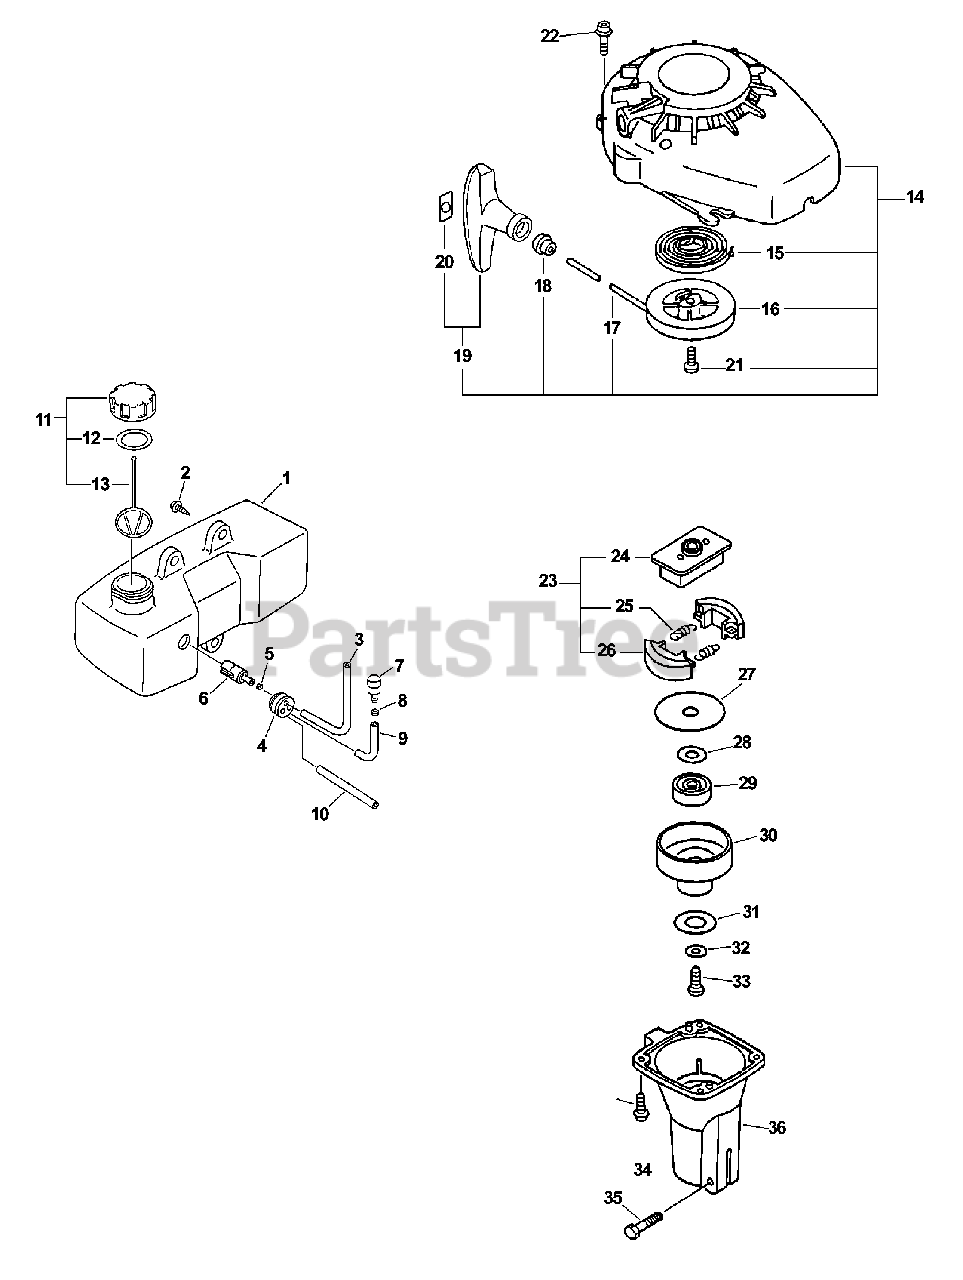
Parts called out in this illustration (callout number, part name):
1	FUEL TANK ASSY
2	SCREW - 5X15
3	PIPE - 3X5X210 -- BLACK
4	GROMMET
5	CLIP - 6
6	FILTER, FUEL
7	VENT, FUEL TANK
8	CLIP - 5.5
9	PIPE - 3X5X70 -- BLACK
10	PIPE - 3X6X50 -- CLEAR
11	CAP ASSY
12	GASKET, CAP
13	CONNECTOR, CAP
14	STARTER ASSY
15	SPRING, REWIND
16	REEL, ROPE
17	ROPE, STARTER - 3X890
18	GUIDE, ROPE
19	GRIP, STARTER
20	RETAINER, ROPE
22	SCREW - 4X16
23	CLUTCH ASSY
24	HUB, CLUTCH
25	SPRING, CLUTCH
26	SHOE, CLUTCH
27	PLATE, CLUTCH
28	WASHER - 10
29	BEARING, BALL - 6000
30	DRUM, CLUTCH
31	WASHER, CLUTCH
32	WASHER, CLUTCH
33	SCREW - 6X12
34	SCREW - 4X14
35	BOLT - 5X25
36	CASE, CLUTCH
